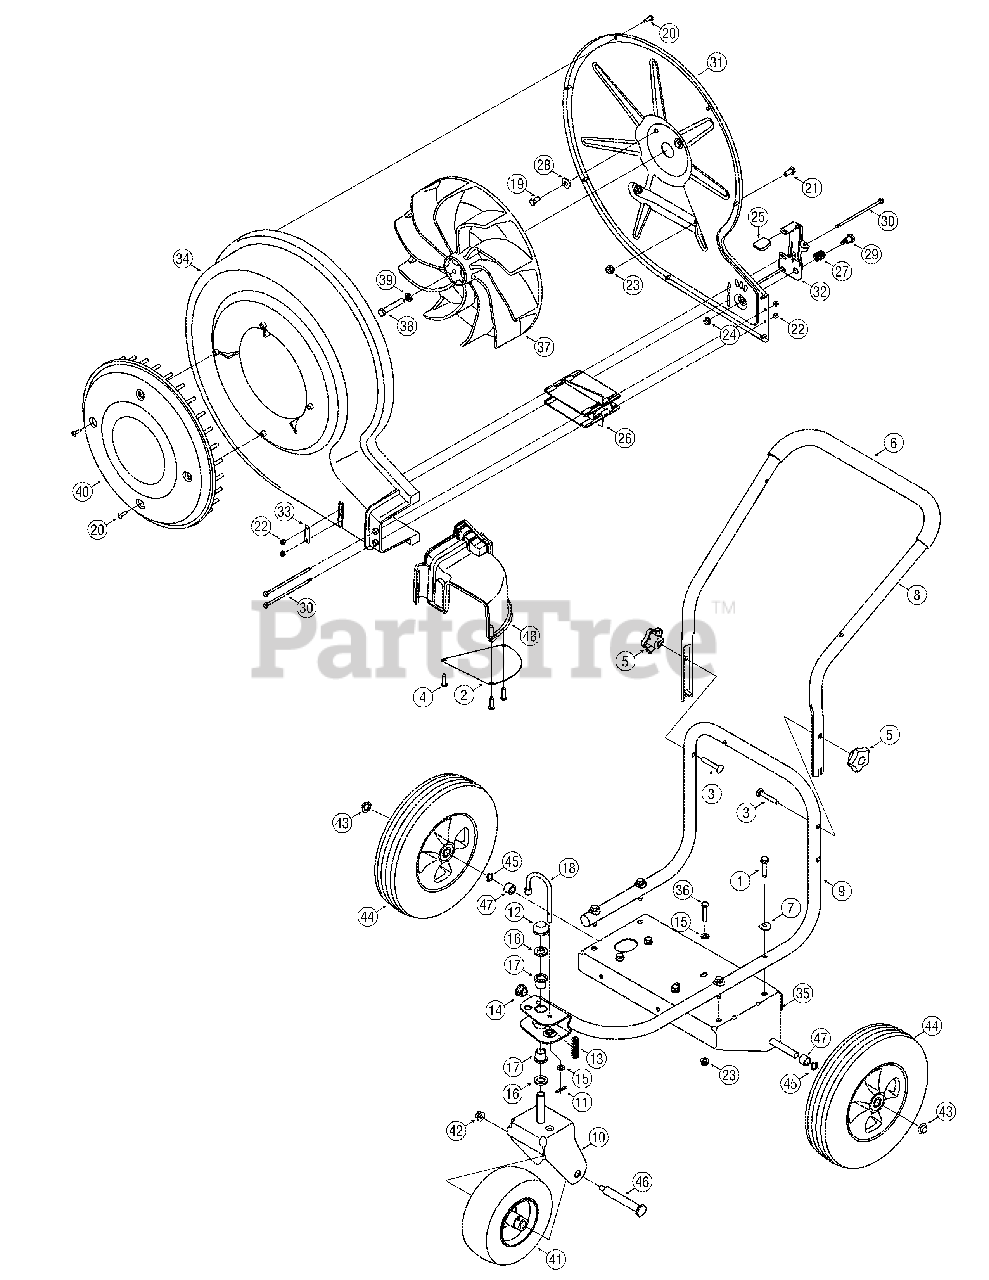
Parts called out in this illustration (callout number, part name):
1	TT Screw, 5/16-18 x 1.50
3	Carriage Screw, 5/16-18 x 2.00
4	Screw, #12-16 x .750
4	Screw, #12-16 x .75
5	Star Knob
7	Saddle Washer, .320 x .93 x .060
11	Cotter Pin
13	Compr. Sprng., .531 OD x 1.75 Lg
15	Washer, Flat, .330 x .630 x .0635
16	Washer, Flat, .640 x 1.12 x .125
17	Flange Bearing, .631 ID
19	Screw, 5/16-24 x .625
20	Screw, #12-16 x .750
20	Screw, #12-16 x .75
21	Screw, 5/16-18 x .75
22	Hexlock Nut, #8-32
23	Flange Lock Nut, 5/16-18
24	Flange Lock Nut, 1/4-20
25	Knob
26	Louver Plate
27	Compr. Sprng., .515 x .641 x .95
28	Bell Washer, .340 x .872 x .060
29	Shoulder Scr., .437 x .13, 1/4-20
30	Shoulder Scr., .18 x 4.8, 8-32
34	Blower Housing
36	Screw, 5/16-18 x 1.50
37	Impeller Assembly
38	Screw, 3/8-24 x 3.25
39	Washer, Lock, 3/8
40	Blower Cover
41	Wheel, 8 x 3
42	Flange Lock Nut, 3/8-16
44	Wheel, 12 x 3
45	Washer, Wave, .510 x .750 x .017
46	Shoulder Screw, .625 x 3.94
47	Spacer, .525 x .775 x .560
48	Chute Attachment
